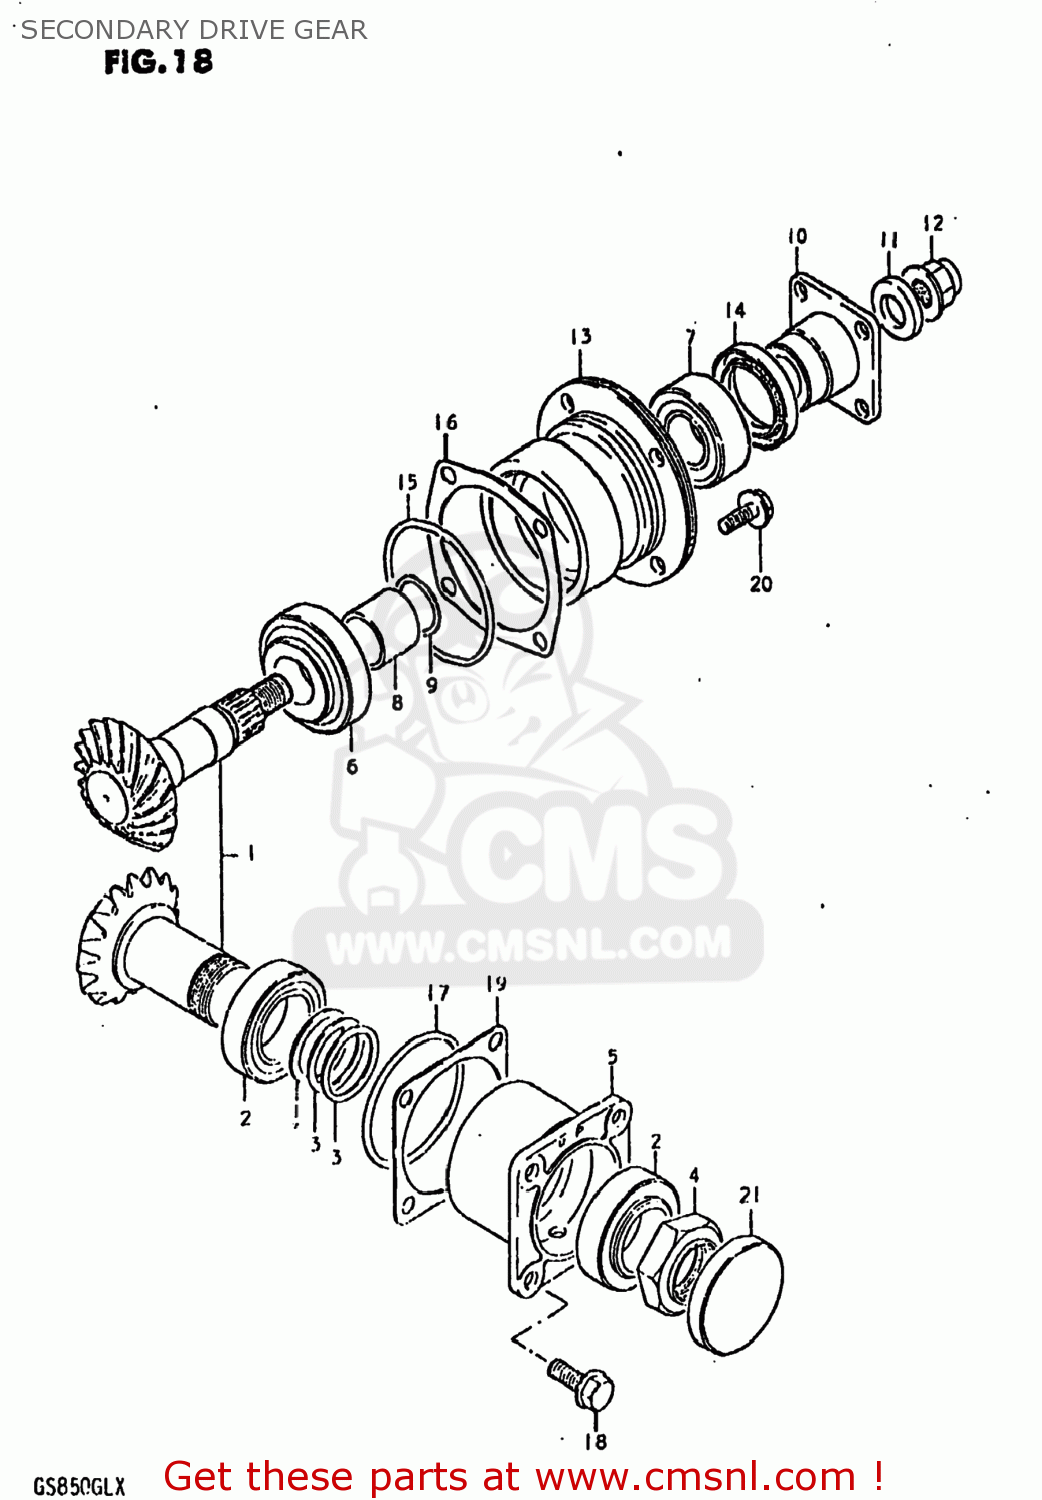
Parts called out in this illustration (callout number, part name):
0	SHIM SET,SECONDARY DRIVE
1	GEAR SET,SECON
2	BEARING(32X58X17)
3	SHIM(32X38X2)
4	NUT
5	HOUSING,SECONDARY DRIVE
6	TAPER,ROLLER BEARING
7	BEARING
8	SPACER (25.2X30X40)
9	SHIM (25X30X2
10	FLANGE,UNIVERSAL JOINT
11	WASHER(14X29X4)
12	NUT
13	HOUSING,SECONDARY DRIVE
14	SEAL,OIL(35X52X9)
15	O RING(D:3.1,ID:69.4)
16	SHIM,DRIVEN GEAR HOUSING
17	O RING(D:2.4,ID:62.6)
18	BOLT
19	SHIM,SECONDARY DRIVE
20	BOLT
21	PLUG
